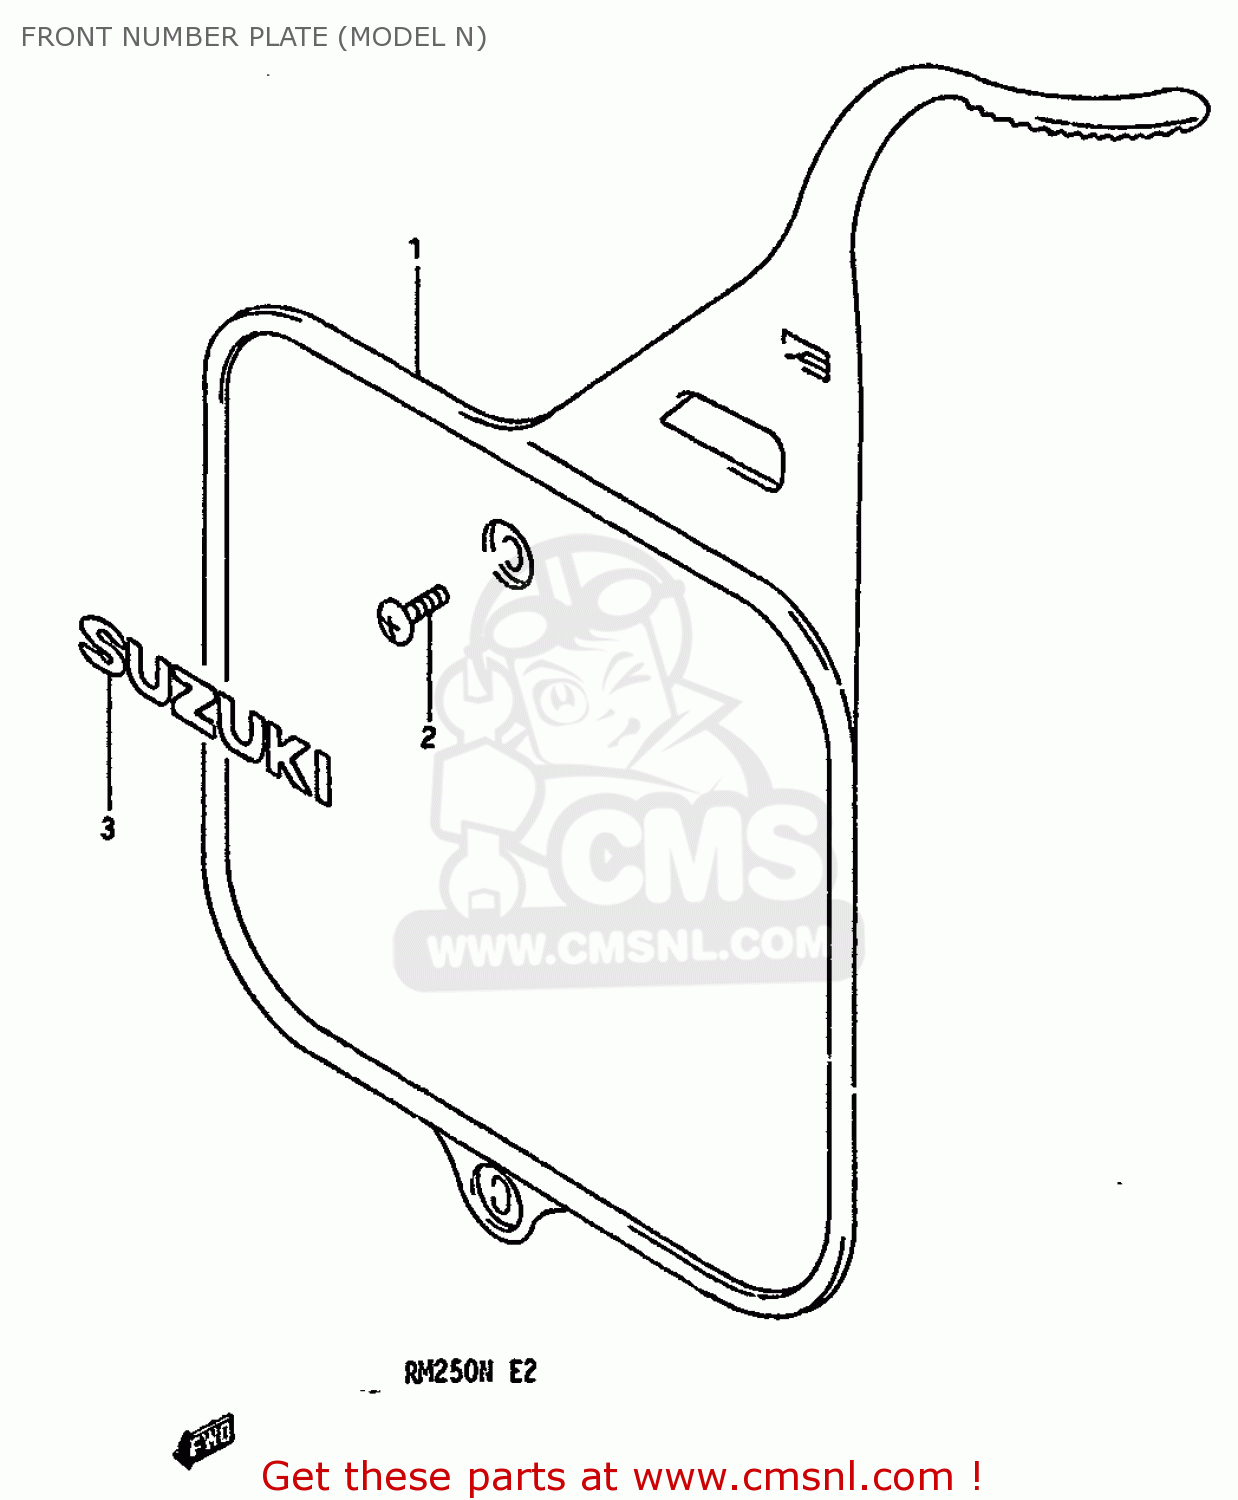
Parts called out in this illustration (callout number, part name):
1	PLATE,NUMBER,FRONT
2	SCREW
3	EMBLEM, SUZUKI
4	EMBLEM,SUZUKI
